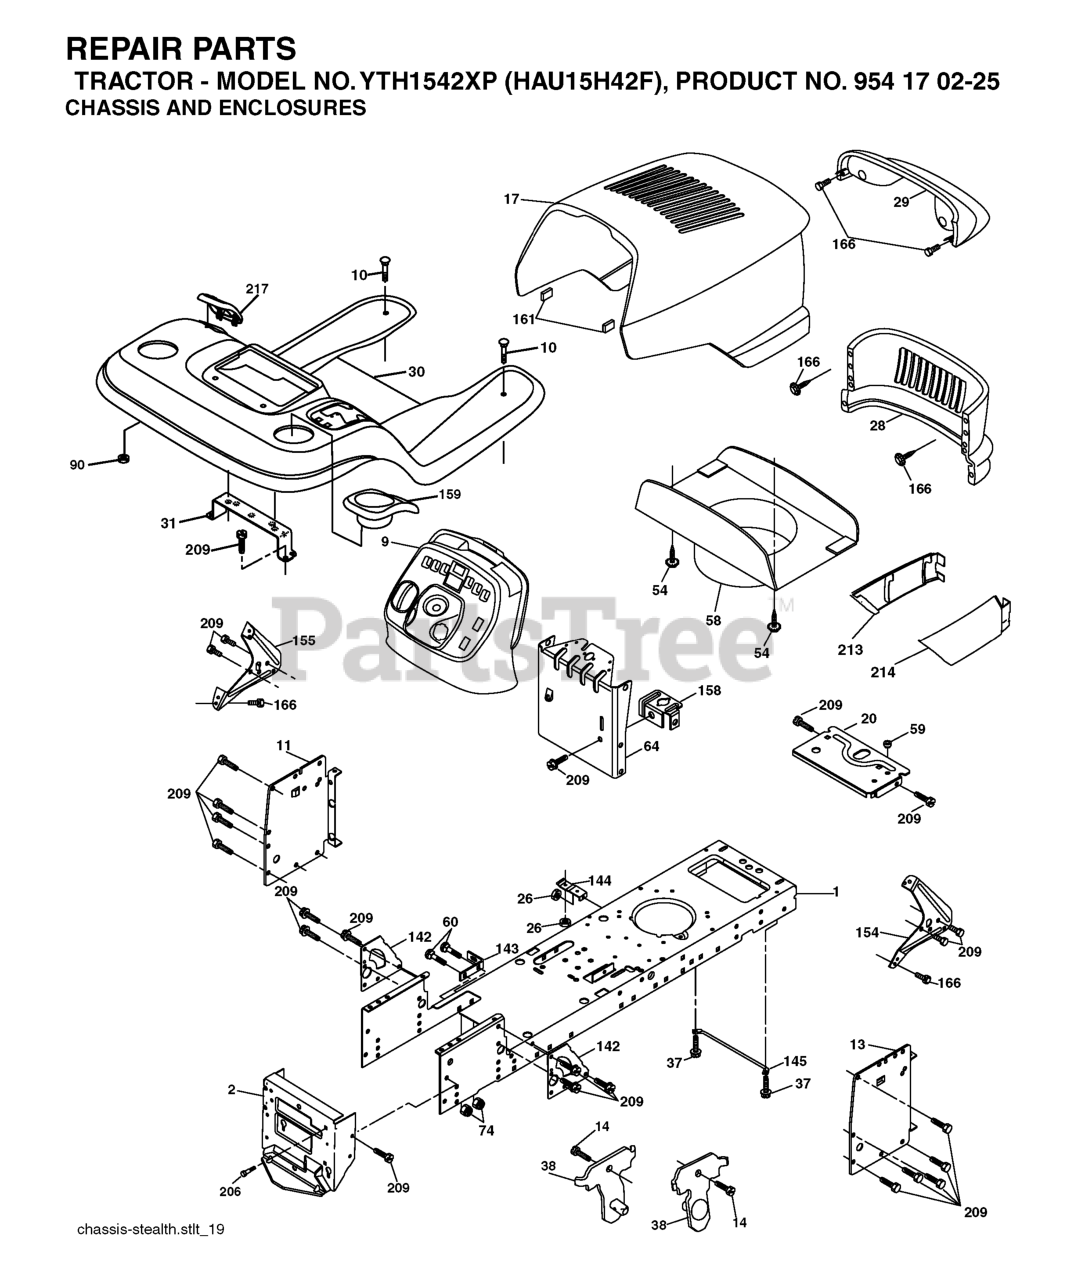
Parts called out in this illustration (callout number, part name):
1	CHASSIS STAMPING
2	DRAWBAR, 12GA
9	DASH, PLASTIC
10	BOLT D
11	PANEL DASH LH
13	PANEL DASH RH
17	HOOD
20	PLATE BATTERY
26	NUT
28	GRILLE.STEALTH P/L.YTGT.GREY
29	LIGHTBOX.ASM.STV.DL.INC.HUSQ
30	FENDER
31	BRACKET.SUPPORT.FENDER
37	Screw 5/16-18 x 1/2 Hex, Self Tapping 5/16-18 x 1/2
38	BRACKET.ASM.PIVOT.MOWER.REAR
54	SCREW.HEX.WS.HD.8-18 X 7/8
59	BUSHING.1.375OD
60	Bolt - Rd. Hd. Sq. Neckiage 3/8 16 x 3/4
64	DASH LOWER
90	NUT.PUSH.3/16
142	PLATE REINFORCEMENT
143	BRACKET, SWAYBAR CHASSIS
144	BRKT, FOOT REST
145	ROD PIVOT CHASSIS/HOOD
154	BRACKET DASH STEALTH(R)
155	BRACKET DASH STEALTH LH
158	BRACKET PARKING BRAKE
159	GREY CUP HOLDER
161	EXTRUSION BUMPER (3 2) (2 2)
166	SCREW
206	SHOULDER BOLT 5/16-18TT
209	SCREW, 3/8-16X3/4
213	SKIRT GRILLE LH
214	SKIRT GRILLE RH
217	CONSOLE FUEL WINDOW
